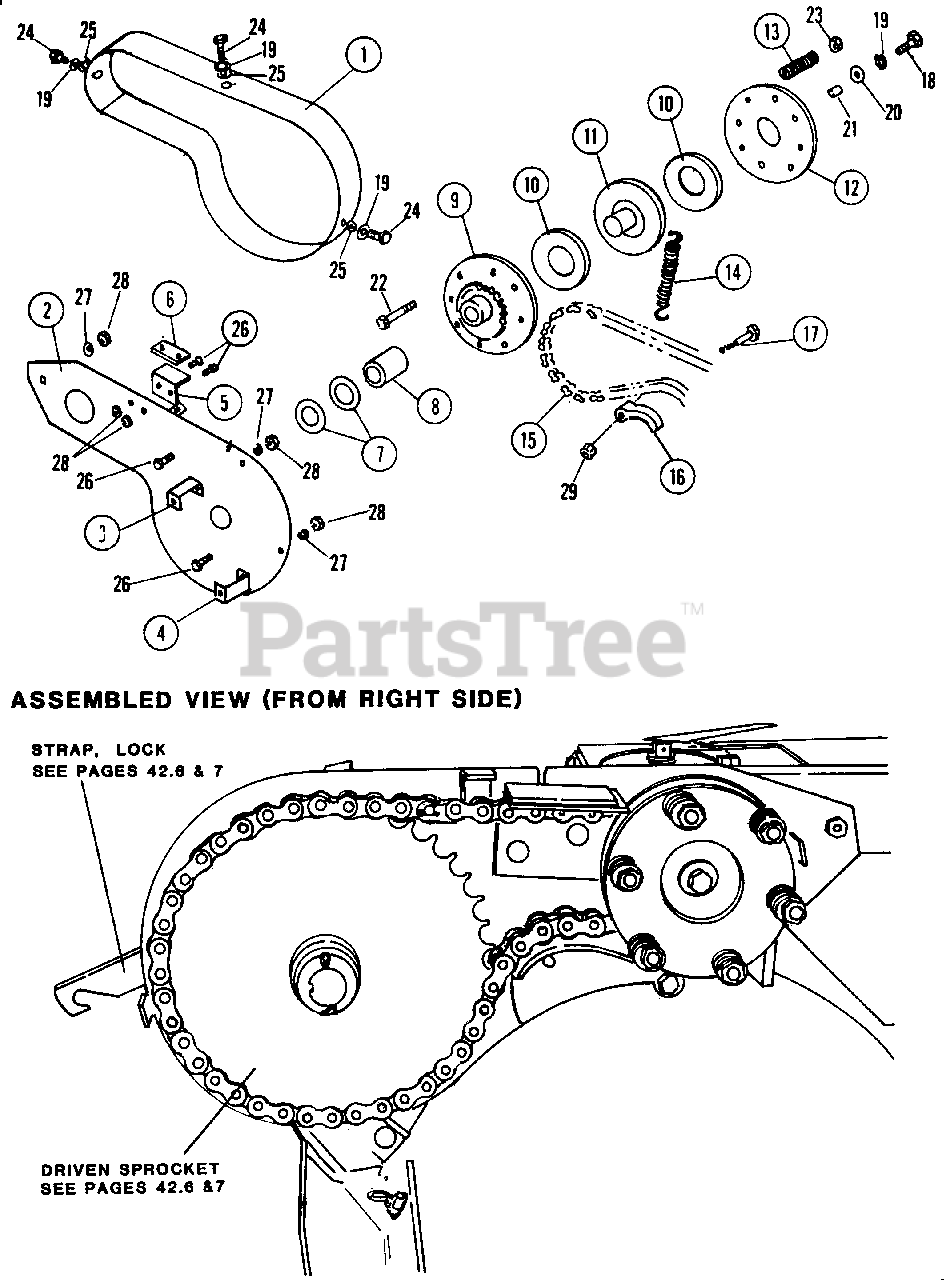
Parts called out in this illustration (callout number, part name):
1	GUARD, OUTER CHAIN
2	GUARD, INNER CHAIN
3	BRACE, UPPER REAR
4	BRACE, LOWER REAR
5	BRACKET, CHAIN DAMPENER
6	PAD, CHAIN DAMPENER
7	WASHER, SPECIAL .765" ID, 1.25" OD, 14 GA.
8	SPACER, SPROCKET - HUB ASSEMBLY 1.503" ID 1.753" OD x 1.0" Bronze
9	SPROCKET & HUB ASSEMBLY
10	DISC, CLUTCH
11	HUB, DISC MOUNTING
12	PLATE, PRESSURE
13	SPRING, TORQUE LIMITER
14	SPRING, EXTERNAL
15	CHAIN, ROLLER #50 / 59 Pitches
16	PADDLE, CHAIN ADJUSTING
17	BOLT, 5/16-18 x 2 HEX HEAD
18	BOLT, 5/16-18 x 3/4 HEX HEAD
19	LOCKWASHER, 5/16 MEDIUM
20	WASHER, SPECIAL .375" ID, 1.0" OD, .104" Thick
21	SPACER, TORQUE LIMITER
22	BOLT, 5/16-18 x 2-1/2 HEX HEAD
23	LOCKNUT, 5/16-18 HEX
24	BOLT, 5/16-18 x 1/2 HEX HEAD
25	WASHER, 5/16 SAE PLAIN
26	BOLT, 1/4-20 x 1/2 SHORT NECK CARRIAGE
27	WASHER, 1/4 SAE PLAIN
28	LOCKNUT, 1/4-20 HEX
29	NUT, HEX 5/16-18
